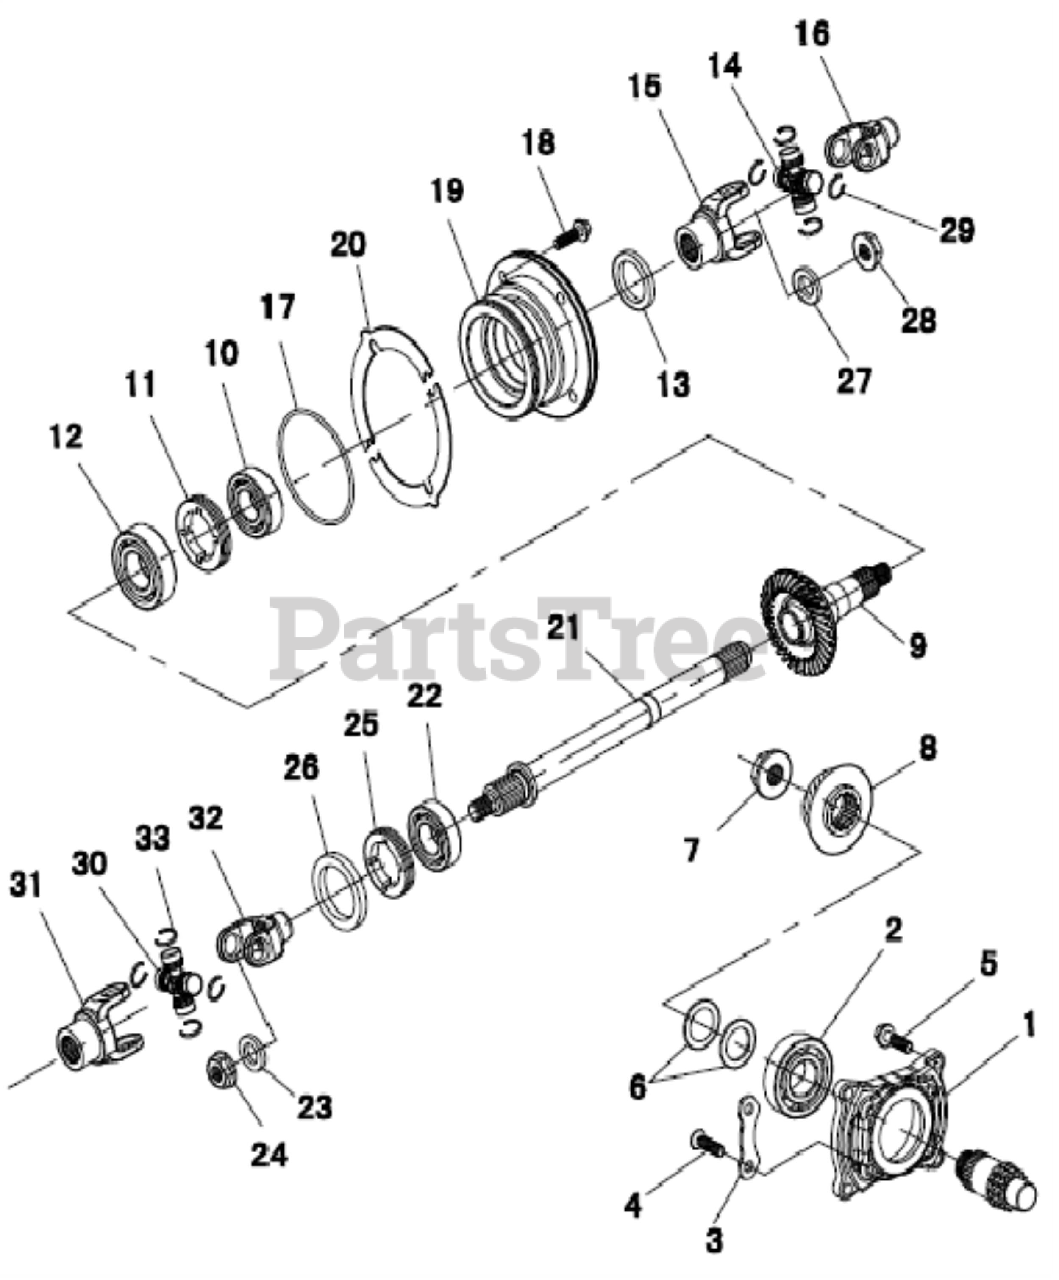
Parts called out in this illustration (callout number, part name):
1	x Shaft Bearing Block
2	Bearing 6305
3	Press Plate,x Shaft Bearing Block
4	Cross recessed countersunk head screw M8x25
5	Hex flange bolts M8x30
6	Spacer 26x38x0.4
7	Hex Flange Nut M22x1
8	Driving bevel gear
9	Driven bevel gear
10	Bearing 63/22
11	External thread nut M60x1.5
12	Bearing 6207
13	Oil Seal 30x46x8
14	Criss-Cross Shaft
15	U-joint A(22?
16	U-joint B(22?
17	O-Ring 88x2.8
18	Hex head bolt & plain washer assemblies M8x30
19	Y Shaft Bearing Block
20	Spacer 0.1,Bevel Gear
20	Spacer 0.3,Bevel Gear
20	Spacer 0.5,Bevel Gear
20	Spacer 0.6,Bevel Gear
21	Y Driveshaft
22	Bearing 6205
23	Washer 14.5x32x5
24	Self-locking Nut M14x1.5
25	External thread nut M55
26	Oil Seal 44x60x7
27	Washer 16.5x28x4
28	Self-locking Nut M16x1.5
29	Grip Ring 22
30	Criss-Cross Shaft
31	U-joint B(22?
32	U-joint A(22?
33	Grip Ring 22
